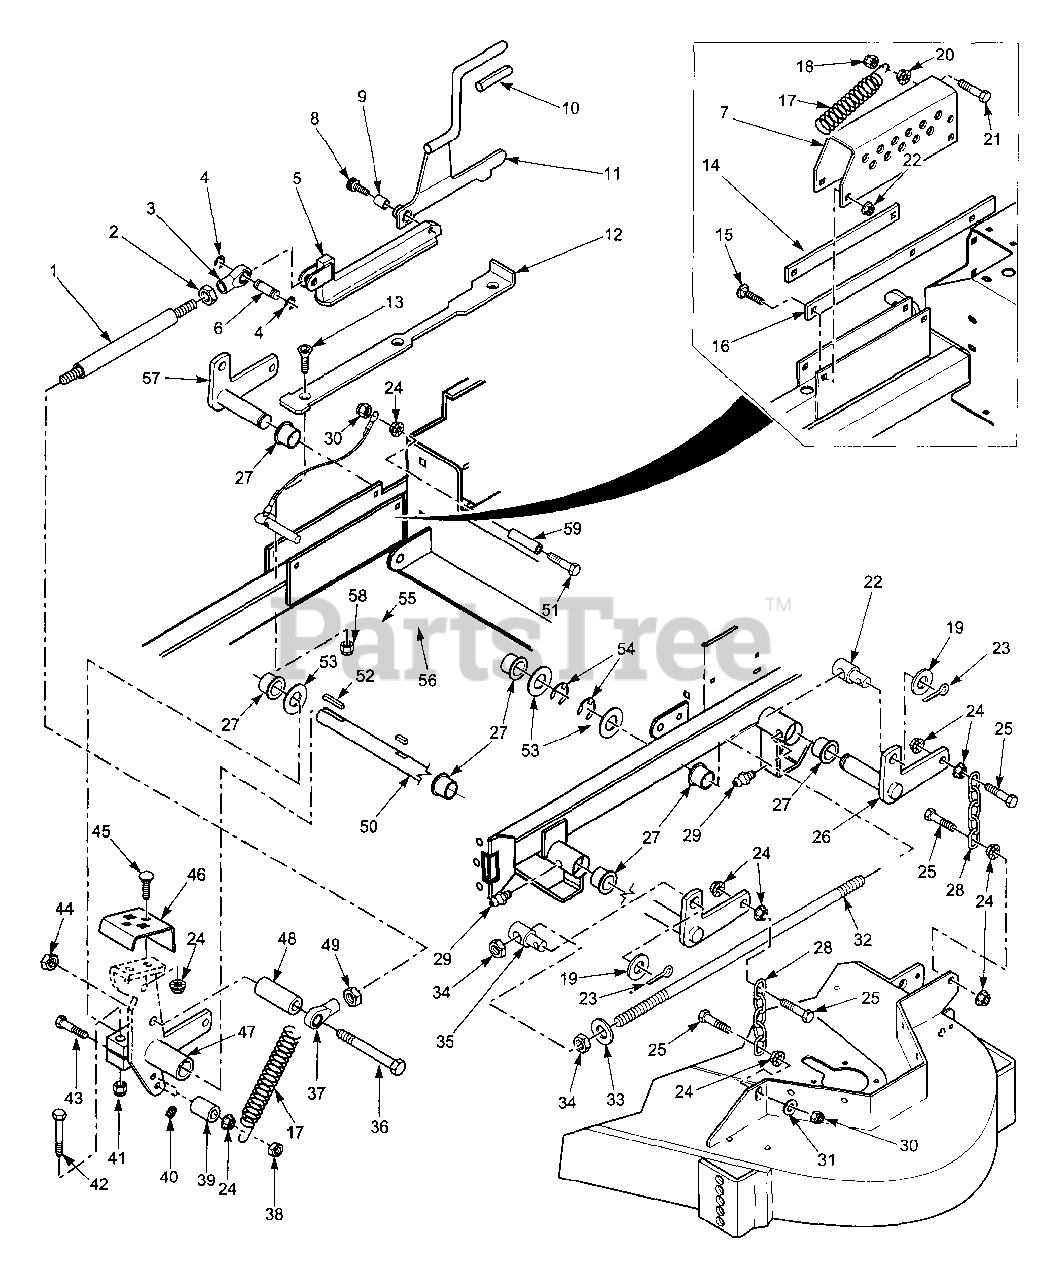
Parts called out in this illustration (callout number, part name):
1	Rod, Deck Lift Linkage
2	Nut, Jam 1/2-20 LH Thread
3	Rod End, 1/2-20 Female Thread
4	Retaining Ring, 1/2" External "E"
5	Slide, Deck Height Adjust
6	Pin, Deck Lift
7	Bracket, Cutting Height Adjustment
8	Bolt, Shoulder 1/2-3/4"
9	Bushing .502 ID
10	Grip, Deck Latch Lever
11	Lever, Deck Latch
12	Slide, Cutting Height
13	Screw, Cap 5/16-18 x 3" FHHS
14	Guide, Short
15	Bolt, Carriage 5/16-18 x 1"
16	Guide, Long
17	Spring, Helper
18	Nut, 3/8-16 Center Lock
19	Flatwasher, 5/8-.656 x 1.312 x .095
20	Nut, 3/8-16 Serr. Flange
21	Bolt, Hex Head 3/8-16 x 1-1/4"
22	Swivel Joint LH
23	Cotter Pin, 3/16 x 1"
24	Nut, Serr Flange 3/8-16
25	Bolt, Hex Head 3/8-16 x 1-1/2"
26	Bellcrank, RH Rear
27	Bushing
28	Chain
29	Grease Fitting, 1/4-28 Self Tap
30	Nut, Elastic Stop 3/8-16
31	Flatwasher, 3/8-.391 x .938 x .105
32	Stud, 5/8-11 x 22"
33	Flatwasher, 5/8-.656 x 1.312 x .095
34	Nut, 5/8-11 UNC
35	Swivel Joint RH
36	Bolt, Hex Head 1/2-13 x 5"
37	Rod End, 1/2-20 Female
38	Lock Nut, 3/8-16
39	Spacer
40	Set Screw, 5/16-18 x 1/4"
41	Nut, Elastic Stop 7/16-14
42	Bolt, Hex Head 7/16-14 x 2-1/2"
43	Bolt, Hex Head 3/8-16 x 2-1/2"
44	Lock Nut, 1/4-20
45	Bolt, Carr. 3/8-16 x 1"
46	Foot Pedal
47	Foot Pedal Weldment
48	Spacer
49	Nut, 1/2-20 UNF-2B
50	Bellcrank, LH Front
51	Bolt, Hex Head 3/8-16 x 3-1/2"
52	Key, 1/4 x 1/4 x 1-1/4"
53	Flatwasher, 1.062 x 1.5 x.048
54	Retaining Ring, 1" Ext.
55	Ring Pin, 1/2 x 3.30"
56	Lanyard, Deck Height Pin
57	Bellcrank, LH Rear
58	Nut, Elastic Stop 5/16-18
59	Spacer
